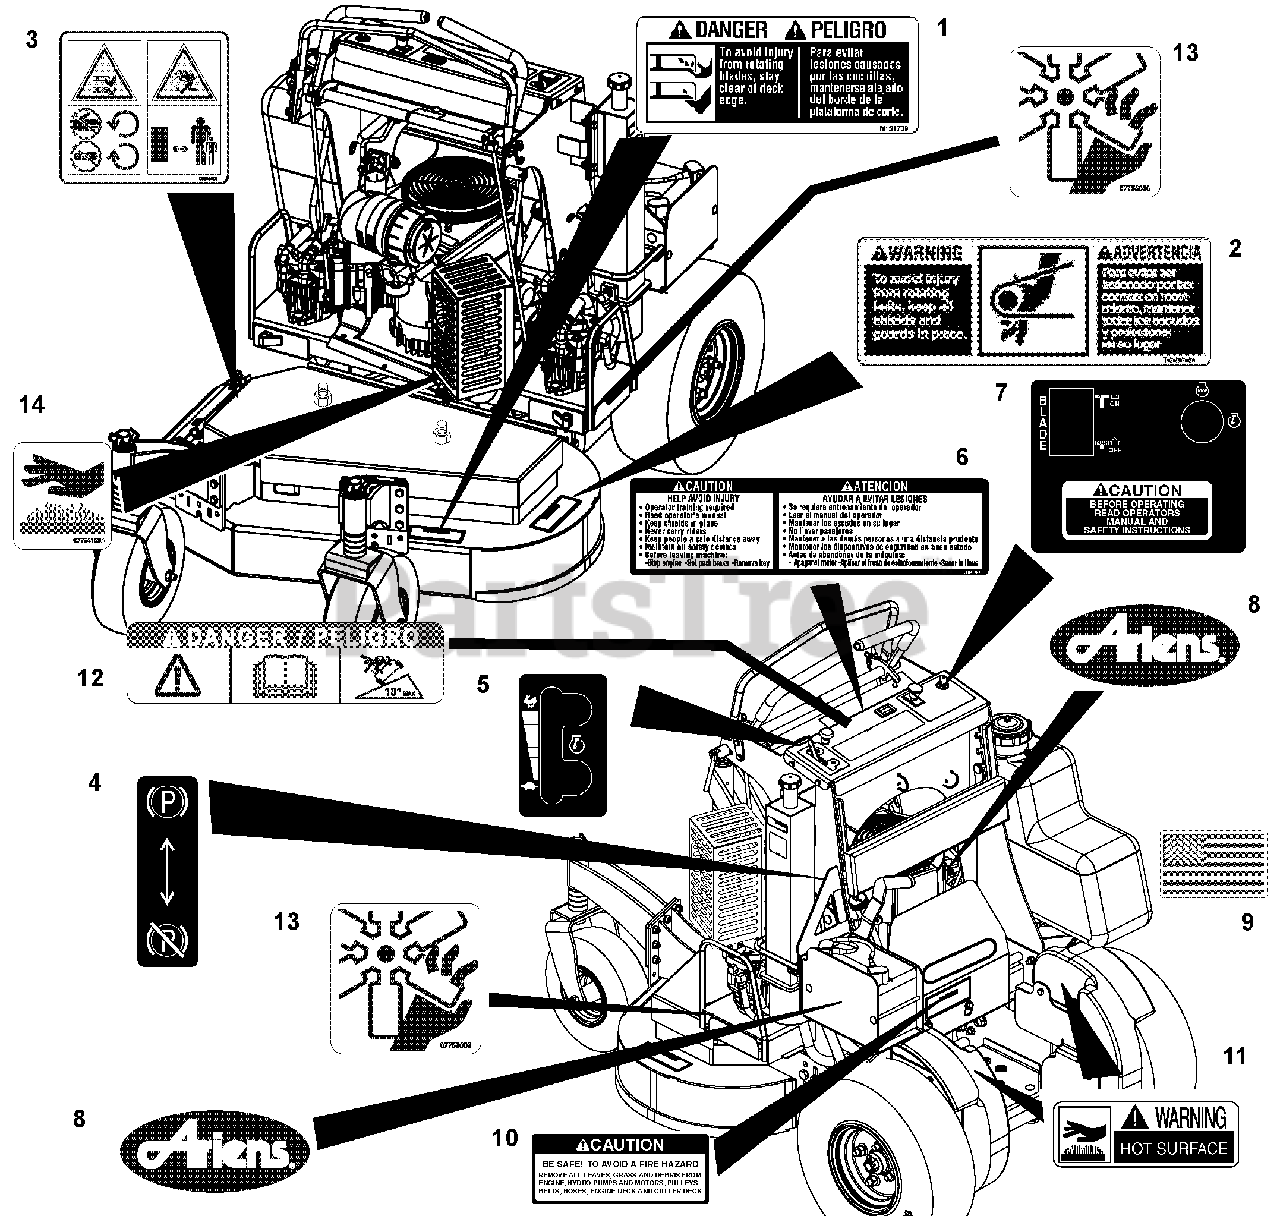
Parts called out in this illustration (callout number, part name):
1	DECAL, DANGER-BLADE CONTACT
2	DECAL, DANGER-ROTATING BELTS
3	DECAL, CE DECK
4	DECAL, PARK BRAKE
5	DECAL, THROTTLE
6	DECAL, GENERAL CAUTION
7	DECAL, PTO/IGNITION
8	DECAL, ARIENS
9	DECAL, AMERICAN FLAG
10	DECAL, CAUTION-FIRE HAZARD
11	DECAL, WARNING-HOT SURFACE (RE
12	DECAL - BILINGUAL DANGER
13	DECAL, DANGER FAN
14	DECAL, HOT SURFACE
